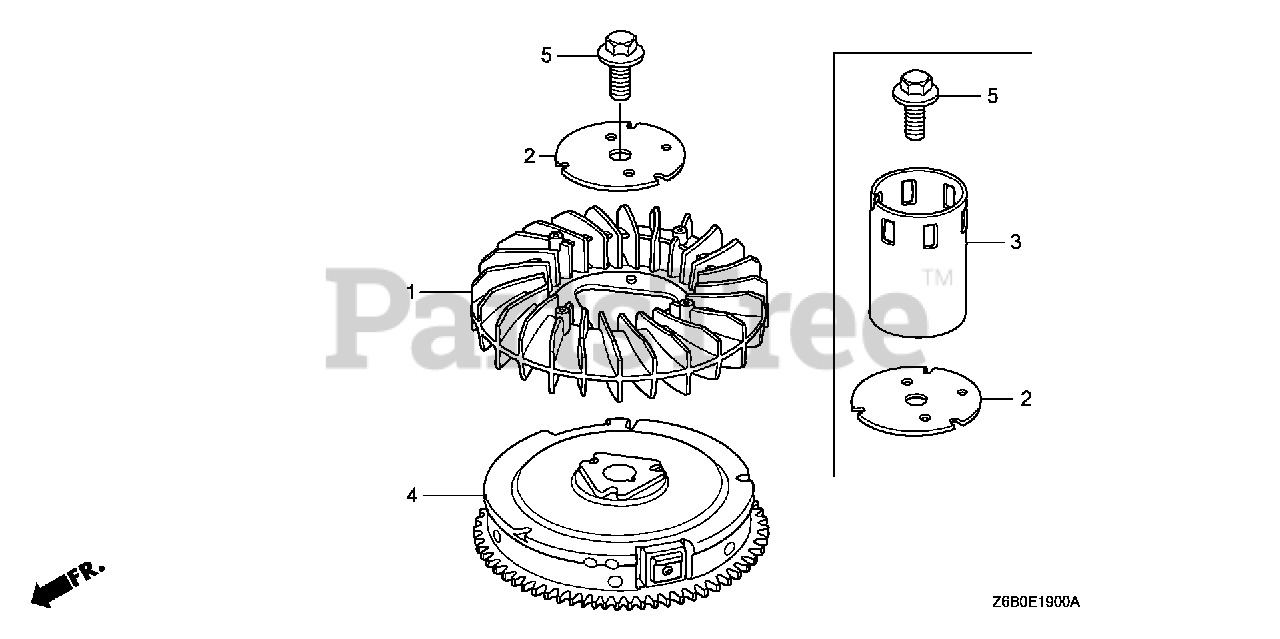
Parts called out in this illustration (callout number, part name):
1	FAN, COOLING
2	PLATE, COOLING FAN SETTING
3	PULLEY, STARTER
5	BOLT, FLANGE (16X35)
